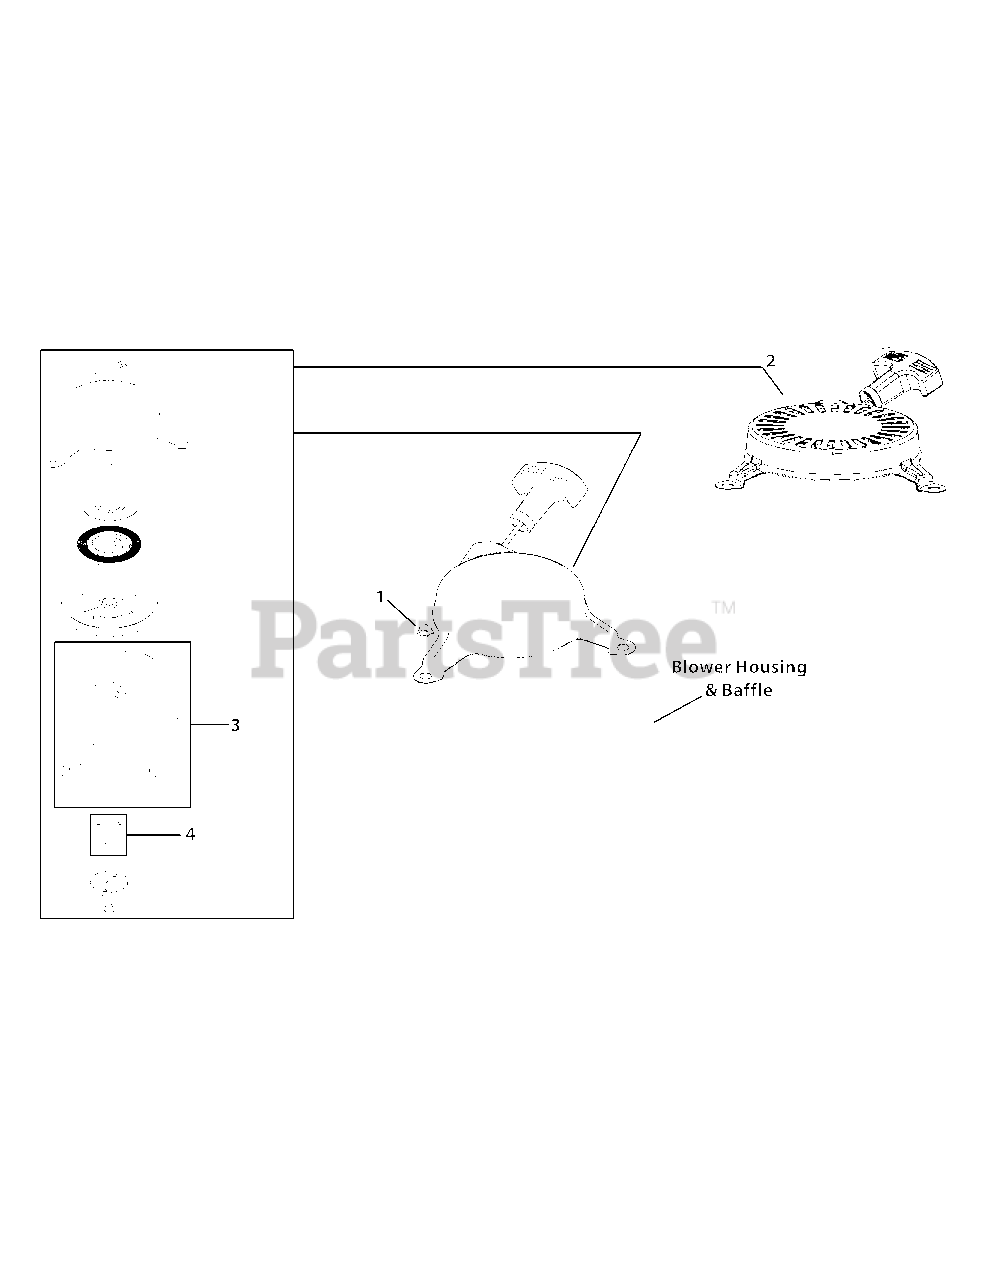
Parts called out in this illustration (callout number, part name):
1	Hex Flange Nut, M6
2	Retractable Starter Assembly
4	Pawl Repair Kit
